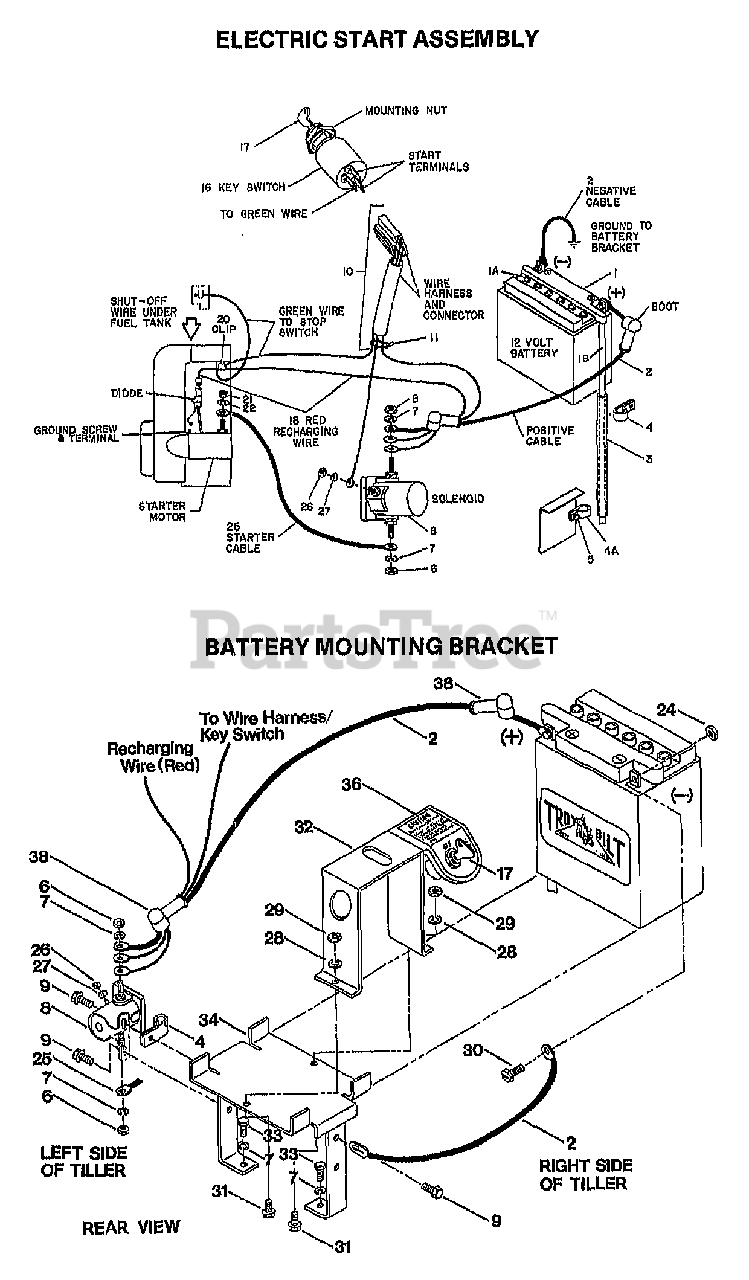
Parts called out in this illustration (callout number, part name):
1	BATTERY (INCL. HARDWARE TO CONNECT BATTERY CABLE TERMINALS TO BATTERY POSTS)
1A	CAP-YELLOW
1A	CAP-BATTERY WHITE (PONY)
1B	TUBE-VENT BATTERY/HSE
2	CABLE-BATTERY (REPLACES #9223)
3	TUBING-RUBBER
4	CLAMP
5	SCR-HHC 5/16-18X.75 GR 5 ZP
6	NUT-HEX 5/16-24
7	WASHER-LK .312 ZP
8	KIT-SOL W/HDW (INCL. NUTS & WASHERS FOR CABLES & WIRES)
9	SCR-HWH 1/4-20 X .5 STH
10	ASSM-HARNESS 2647/20857 (AVAIL. AS COMPLETE UNIT ONLY)
11	TIE-TWIST LOCK
16	KEYSWITCH W/KEYS
17	KEYS(1 PAIR) FOR SWITCH
18	WIRE-RECHARGE 5&7 BRIGGS
20	CLIP-SPECIAL
21	NUT, HEX #10-24 (NOT AVAIL. FORM GARDEN WAY)
22	LOCKWASHER #10 (NOT AVAIL.FROM GARDEN WAY)
24	NUT (USE #9800 OR EQUIV.)
25	CABLE-STARTER
26	NUT-HH M10-32X.125
27	WASHER-EXTERNAL TOOTH 1
28	WASHER-LK .25 ZP
29	NUT-HEX 1/4-20 ZP
30	BOLT, HEX (USE #9775 OR EQUIV.)
31	SCR-CARR 1/4-20X1.25
32	PLTE-KEYSWITCH W/DECAL #20418 -PONY 3
33	SCR-HH 5/16-18X1.0 G5 ZP
34	BRKT-BATTERY PNT
36	DECAL-KEYSWITCH TILLER
